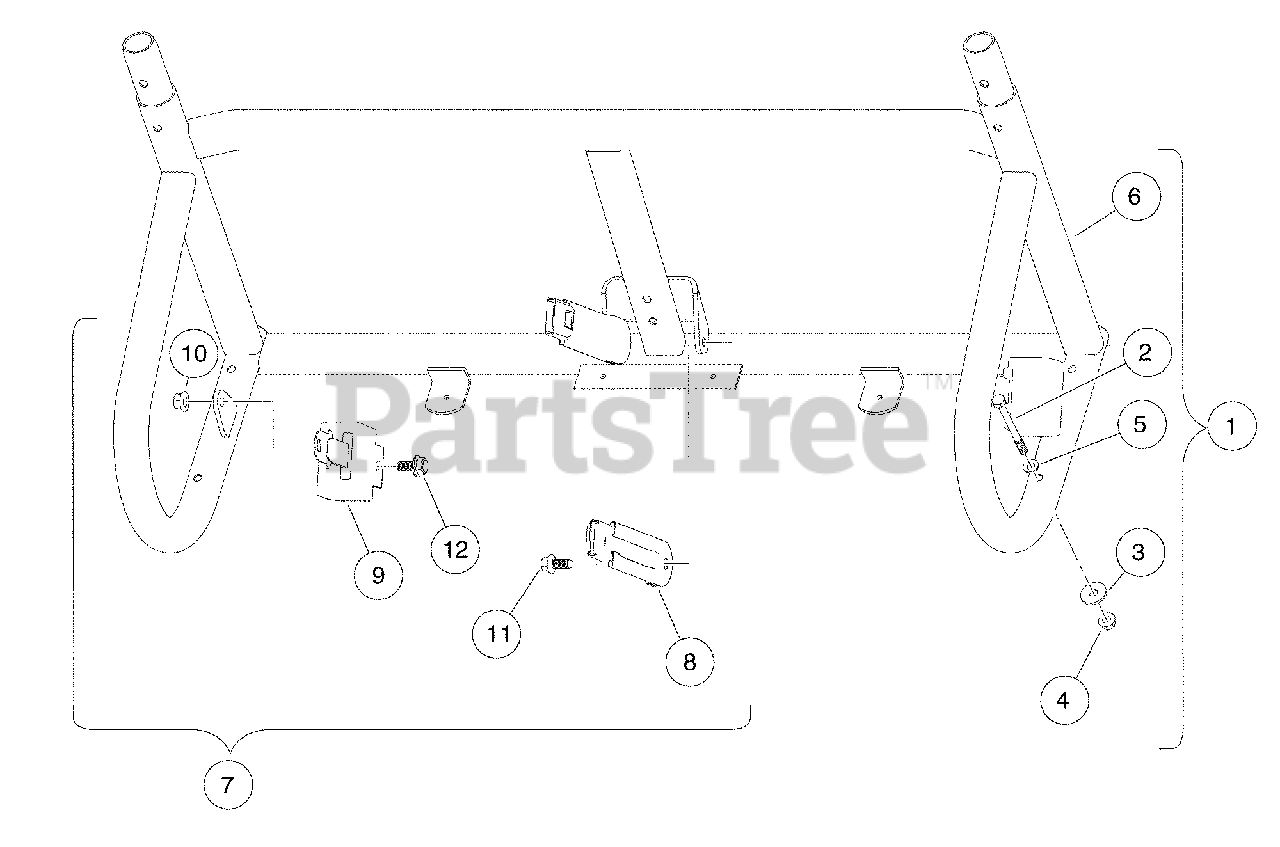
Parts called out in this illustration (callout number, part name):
1	Instl, Rops, Lower
2	Bolt, M10x1.50x100 (Black)
3	Washer Hard,m10
4	Nut Flg M10 X 1.5 Mech Def
5	Washer, Hard, M10, Zn-Ni/Blk
6	Weldment,seat Support,hs,rops
7	Instl, Seat Belt, Restyle
8	Buckle, Seat Belt with Sleeve
9	Retractor, Seat Belt
10	Ln Flg, M12 X 1.75, Md, Black
11	Screw,m12x1.75x30 Thd Form Blk
12	Bolt Flg, M12x1.75 X 25 Black
